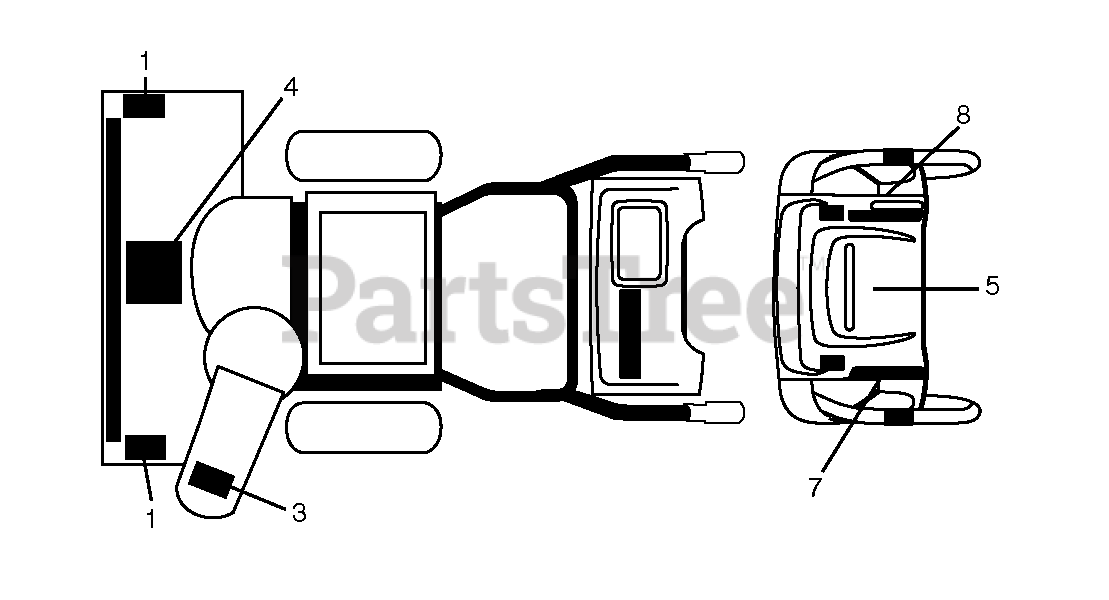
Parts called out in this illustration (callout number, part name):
1	DECAL.SNOWTHR.AUGER
3	DECAL.SNOWTHR.CHUTE.SAFETY
4	DECAL.SNOWTR.READ.OWN.MAN.E/F
5	DECAL.CONSOLE.SNOW.INST.ENG/FR
7	DECAL.CONS.LT.SPD/LEV/PWRST.
8	DECAL.CONS.RT.SPD/LEV/PWRST.
